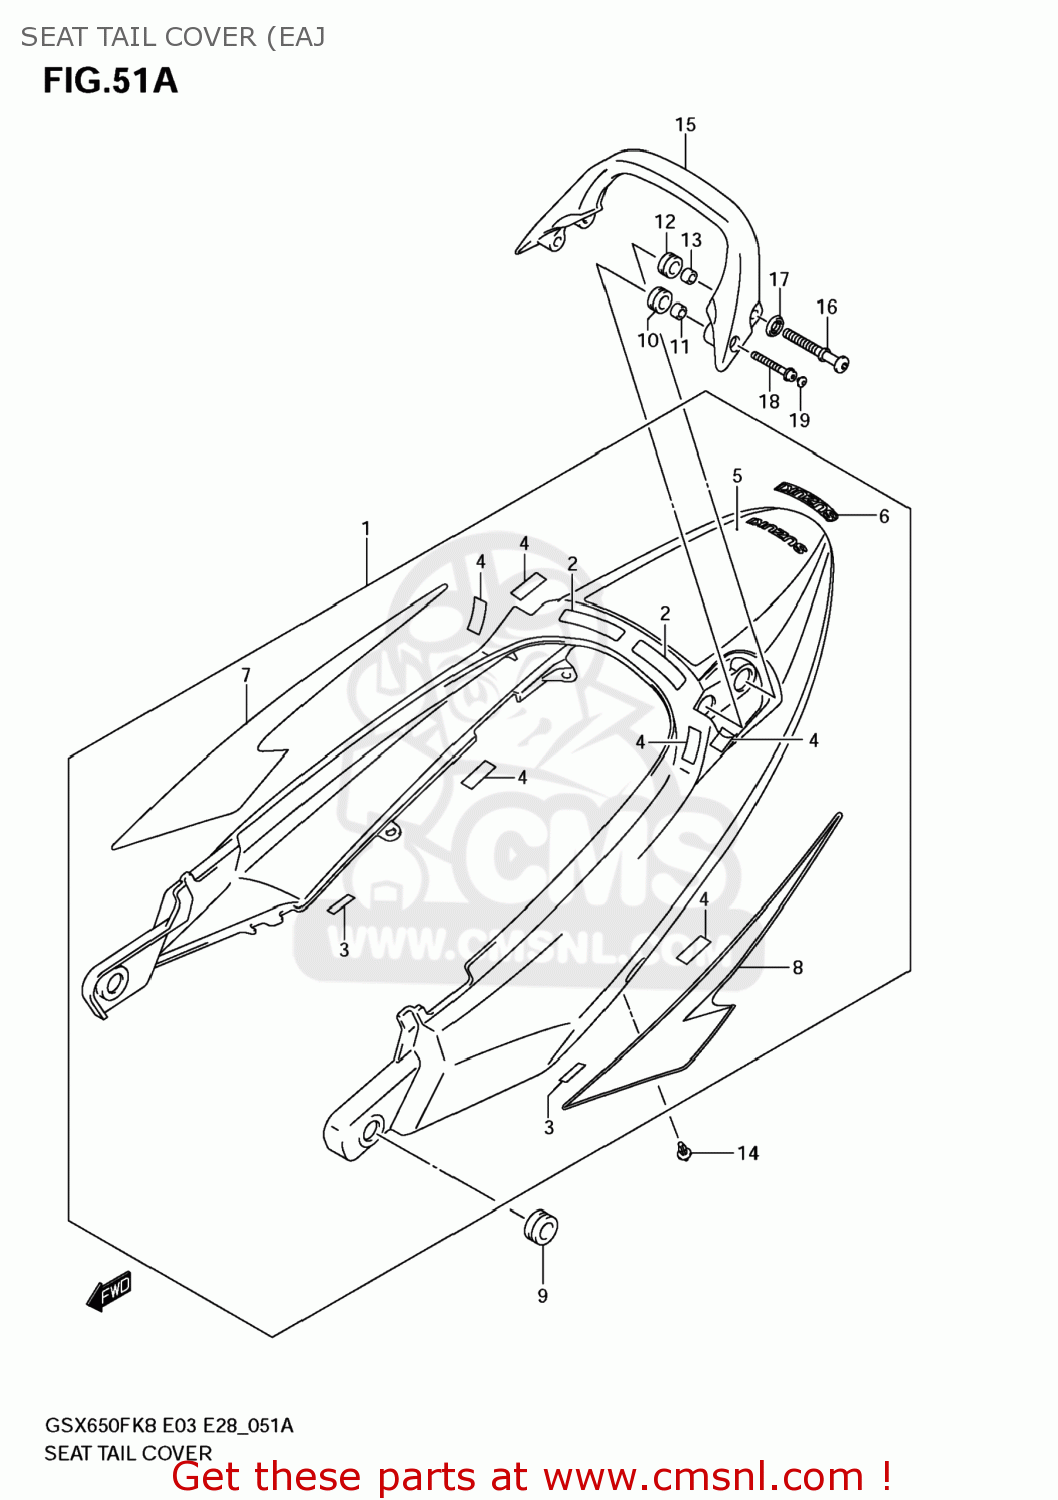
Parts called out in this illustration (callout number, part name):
1	COVER ASSY,SEAT TAIL(WHITE)
2	TAPE,COVER
3	TAPE,SEAT TAIL COVER
4	PROTECTOR,FRAME COVER
5	TAPE,SEAT TAIL COVER CTR
6	EMBLEM,SUZUKI
7	TAPE,SEAT TAIL COVER,R
8	TAPE,SEAT TAIL COVER,L
9	CUSHION
10	CUSHION
11	SPACER(6.5X12X9)
12	CUSHION
13	SPACER,8.5X14X9
14	CLIP(BLACK)
15	HANDLE,PILLION
16	HOOK,PILLION RIDER HANDLE
17	WASHER,HOOK
18	BOLT
19	CAP(OD:10)
